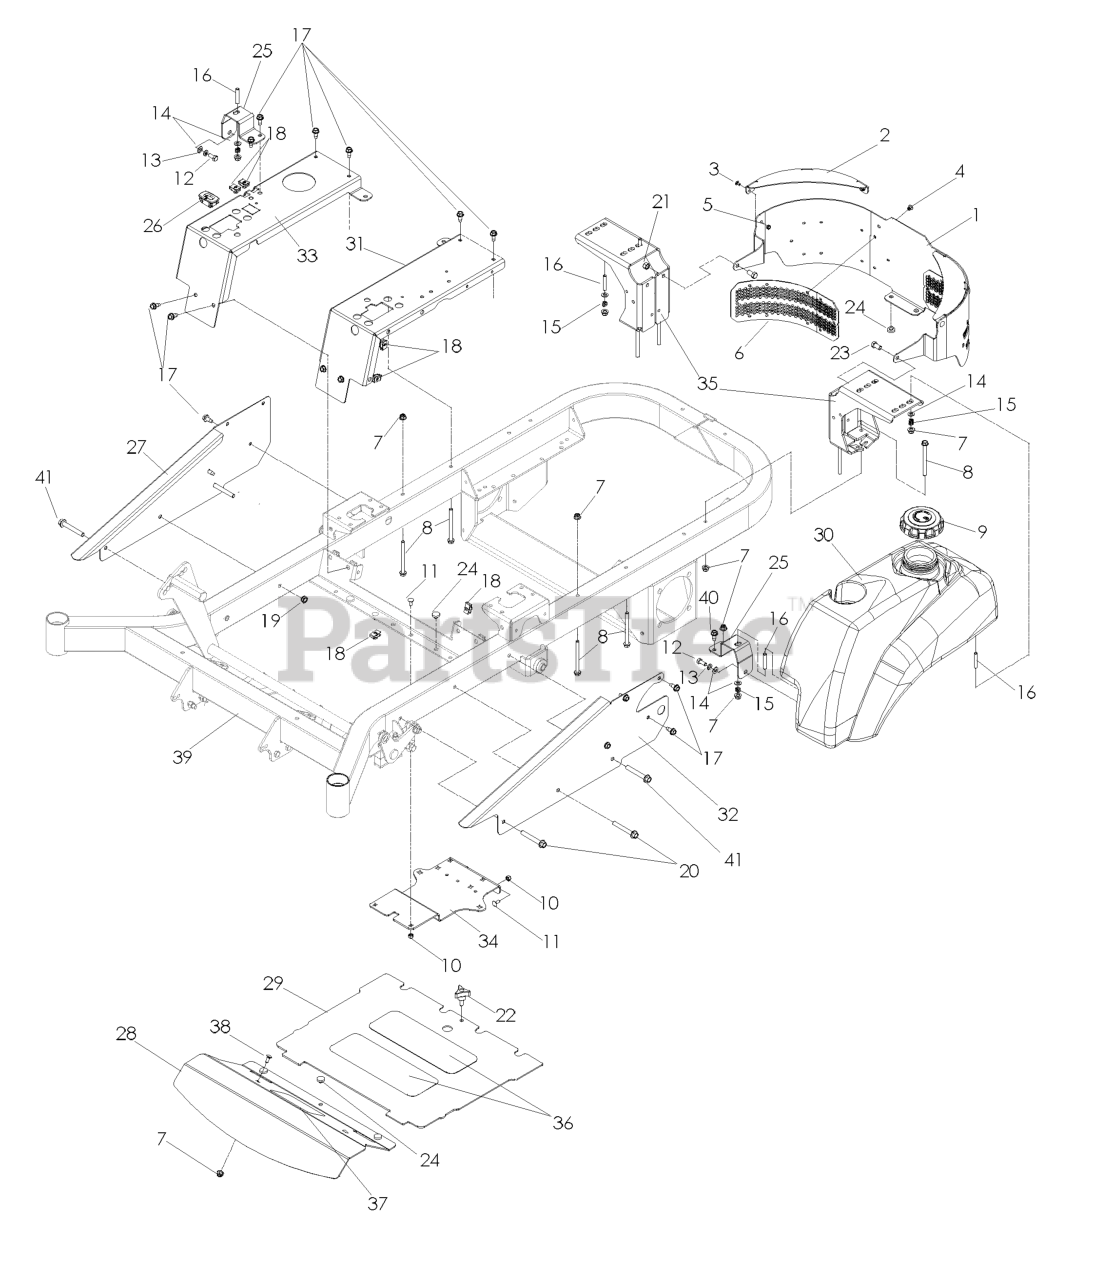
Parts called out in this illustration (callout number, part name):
1	GUARD, REAR
2	SUPPORT, TOP
3	RHSSNB 1/4-20 X 1/2
4	RIVERT, 3/16, STAVEX
5	JAM NUT 1/4C (2 2 PW01)
6	PANEL, HEX, RR
7	5/16-18 NYLOC FLANGE NUT
8	HHFS 5/16-18 X 3 3/4
9	FUEL CAP ANTI-SPLASH
10	NUT.1/4-20.HEX.NYLOC.ZD
11	RHSSNB, 1/4-20X5/8
12	HCS 5/16C X 3/4
13	WASHER.LOCK.HVY.HLCL.SPR.5/16
14	FLAT WASHER 5/16 SAE
16	STUD, 5/16C
17	BOLT 5/16-18 X 3/4
18	U-CLIP 5/16-18 NUT RETAINER
19	NUT HEX 3/8-16 NYLON, THIN
20	HHFS 3/8-16 X 2 3/4
21	NUT 3/8-16 NYLOC
22	KNOB W/STUD
23	SCREW 3/8C X 3/4 HEX CAP
24	GROMMET, BUMPER
25	SUPPORT, TANK, BLK
26	HOUR METER
27	SIDE.RT.ORANGE
28	PLATE, FOOTREST
29	PLATE, FLOOR W/DECALS
30	LEFT TANK W/CUP HOLDER
31	PANEL, FILLER, LT
32	SIDE.LT.ORANGE
33	PANEL, FILLER, RT
34	BATTERY MOUNT
35	MOUNT, TANK, RR
36	ANTI-SKID PAD
38	RHSNB 5/16C X 1
39	FRAME W/DECALS 52", 61"
39	FRAME W/DECALS 72"
40	RP BLT 5/16-18 X 1 THRD FORM D
41	HHFS 3/8-16 X 2.5 GR 5 ZD
